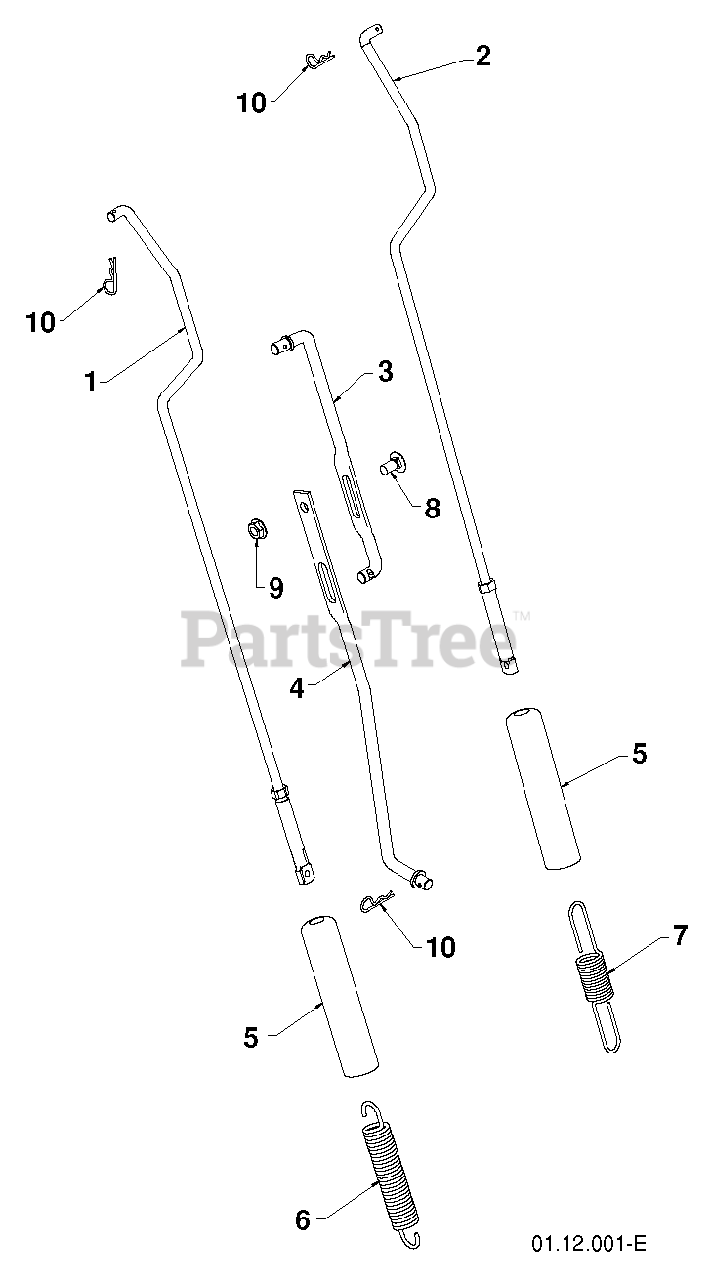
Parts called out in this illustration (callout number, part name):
1	Impeller Control Rod, Snow
2	ROD.TRACTION.CONTROL.SNOW
3	ROD, UPPER SPEED CONTROL
4	ROD, LOWER SPEED CONTROL
5	SLEEVE, SPRING
6	SPRING.CONTROL.ROD.SNOW
7	SPRING.TRACTION.ROD.SNOW
9	NUT.FLANGE.5/16
10	SPRING RETAINER
